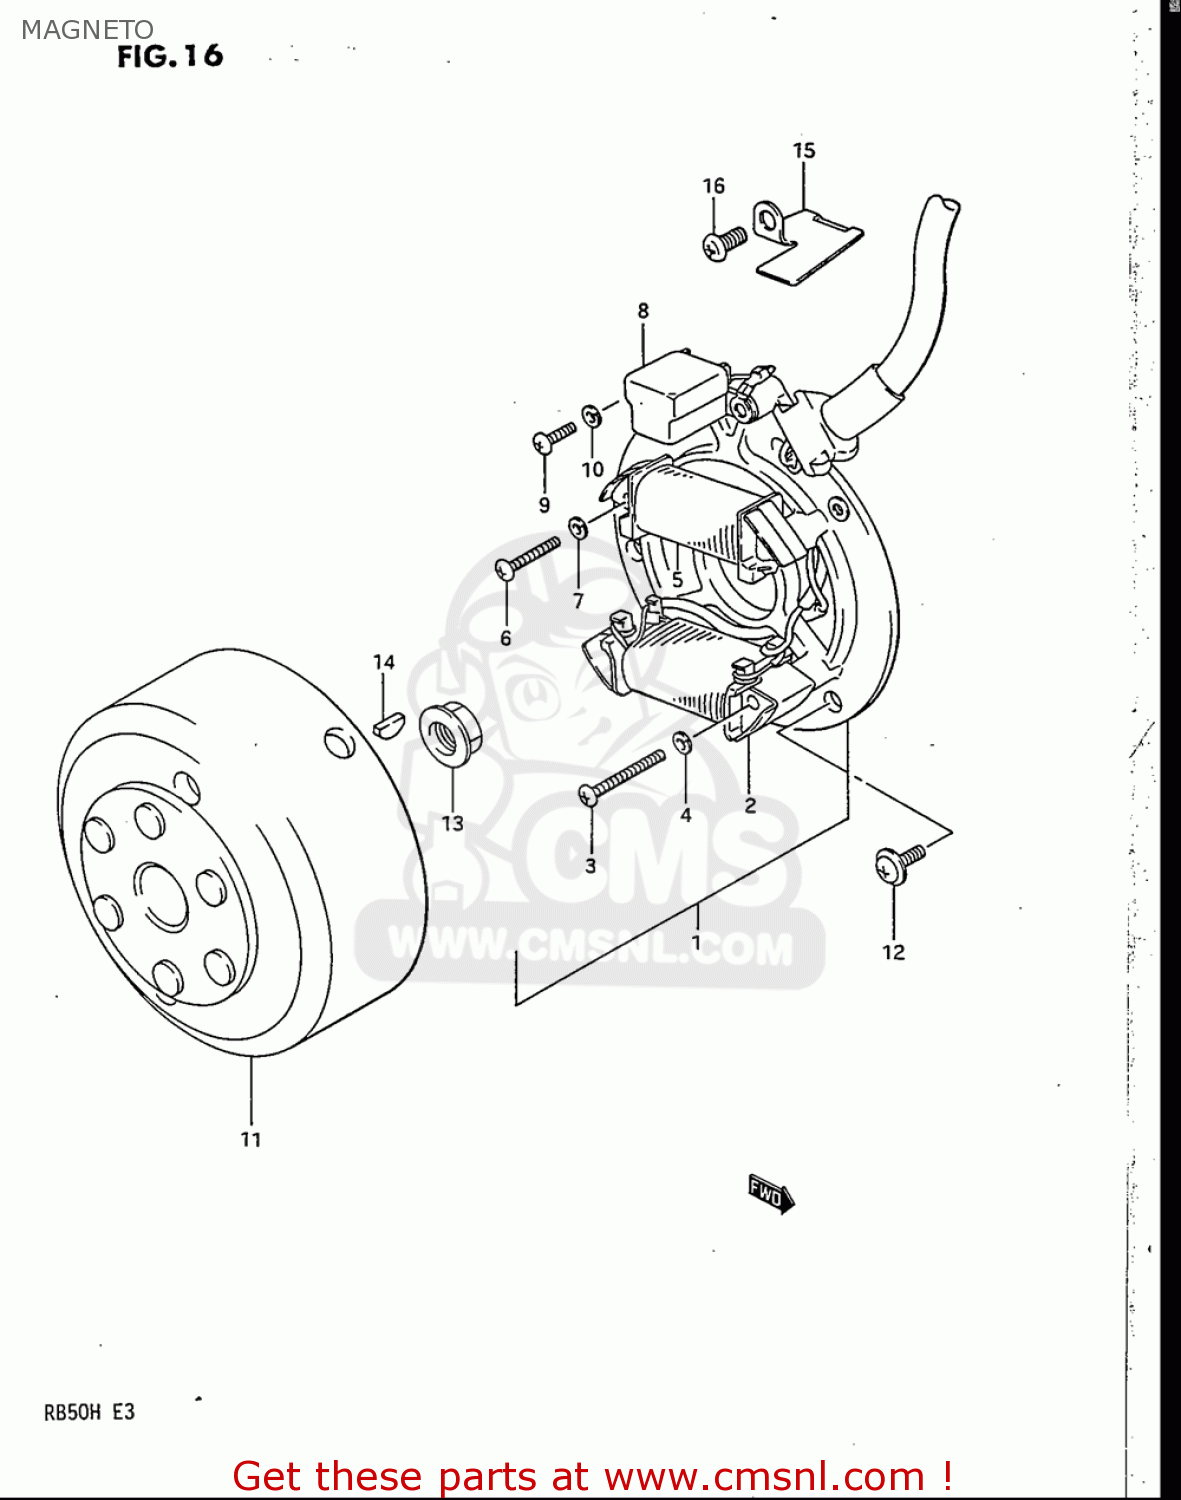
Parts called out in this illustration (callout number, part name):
1	STARTER ASSY
2	COIL,LIGHTING
3	SCREW(4X30)
4	WASHER,LOCK
6	SCREW
7	WASHER,LOCK
9	SCREW
10	WASHER,LOCK
12	SCREW
13	NUT
14	KEY
16	SCREW
